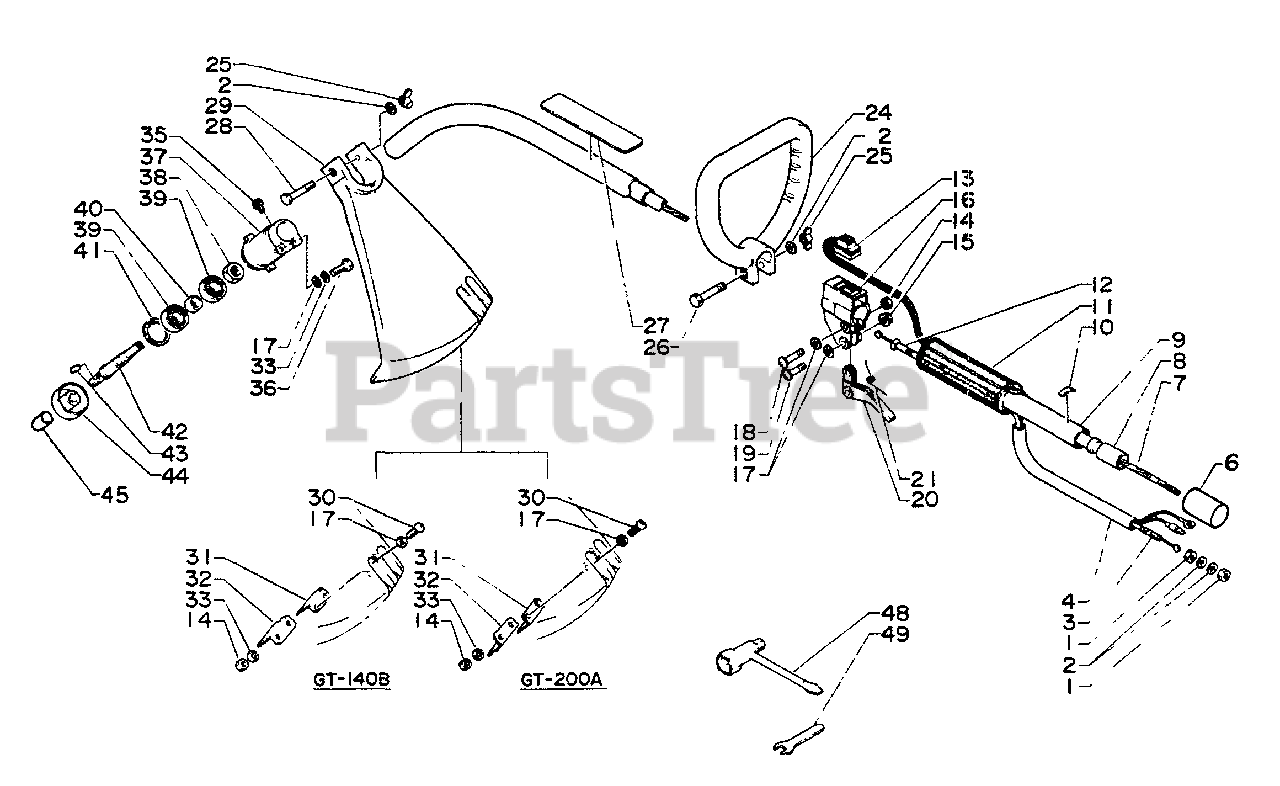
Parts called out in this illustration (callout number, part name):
2	WASHER - 6
3	CABLE, THROTTLE
4	TUBE
6	Cap, housing
7	DRIVESHAFT - FLEXIBLE
8	BUSHING
9	PIPE, MAIN
10	LABEL - ALIGNMENT
11	GRIP, HANDLE
12	GUIDE, CABLE
13	IGNITION SWITCH ASSY
15	LOCKNUT - 5
16	BRACKET, THROTTLE
17	WASHER - 5
18	SCREW - 5X30
19	SCREW - 5X30
20	TRIGGER, THROTTLE
21	SPRING, TRIGGER
24	HANDLE ASSY
25	WINGNUT - 6
26	BOLT - 6X40
27	LABEL - CAUTION
28	BOLT - 6X50
29	SHIELD, DEBRIS - PLASTIC
30	SCREW - 5X14
31	KNIFE, TRIMMER LINE
33	LOCKWASHER - 5
35	SCREW - 4X10
36	BOLT - 5X25
37	CASE, GEAR
38	NUT - 12 -- LEFT HAND
39	BEARING, BALL - 6001 DDU
41	RING, RETAINING - 28
42	GEAR - SHAFT
43	PIN - 3X6
44	ADAPTOR, BLADE - UPPER
45	CAP, DRIVESHAFT
48	T-WRENCH - 8X19mm
49	SPANNER - 10mm
